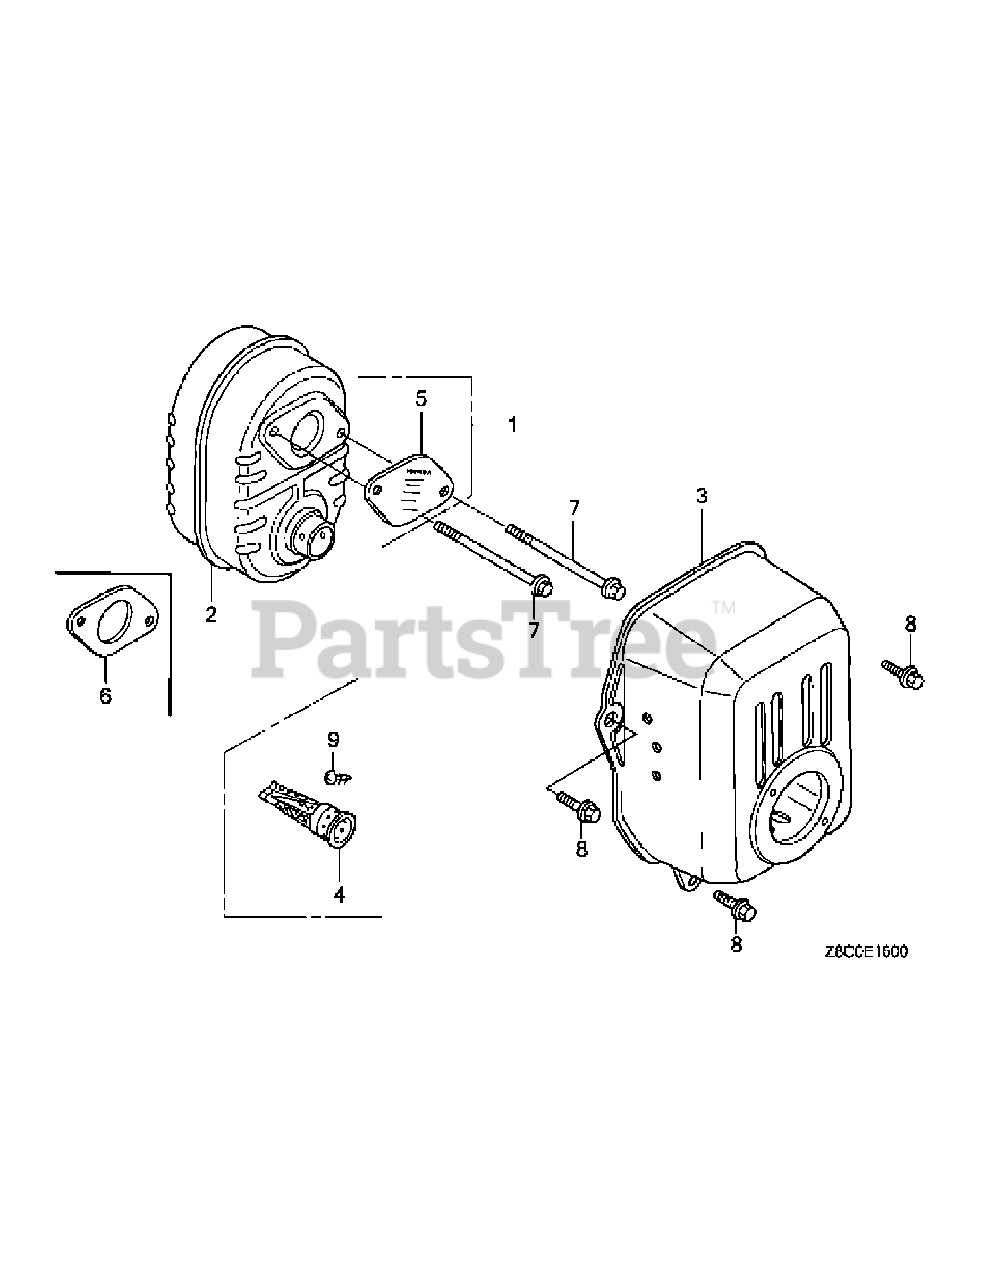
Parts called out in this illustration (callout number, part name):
1	Arrester Kit, Spark
2	Muffler Comp.
3	Protector, Muffler
4	Arrester Comp., Spark
5	Plate, Arrester Number
6	Gasket, Muffler
7	Bolt, Flange, 6X79 (Ct200)
8	Bolt, Flange, 6X12 (Ct200)
9	Screw, Tapping, 4X6
